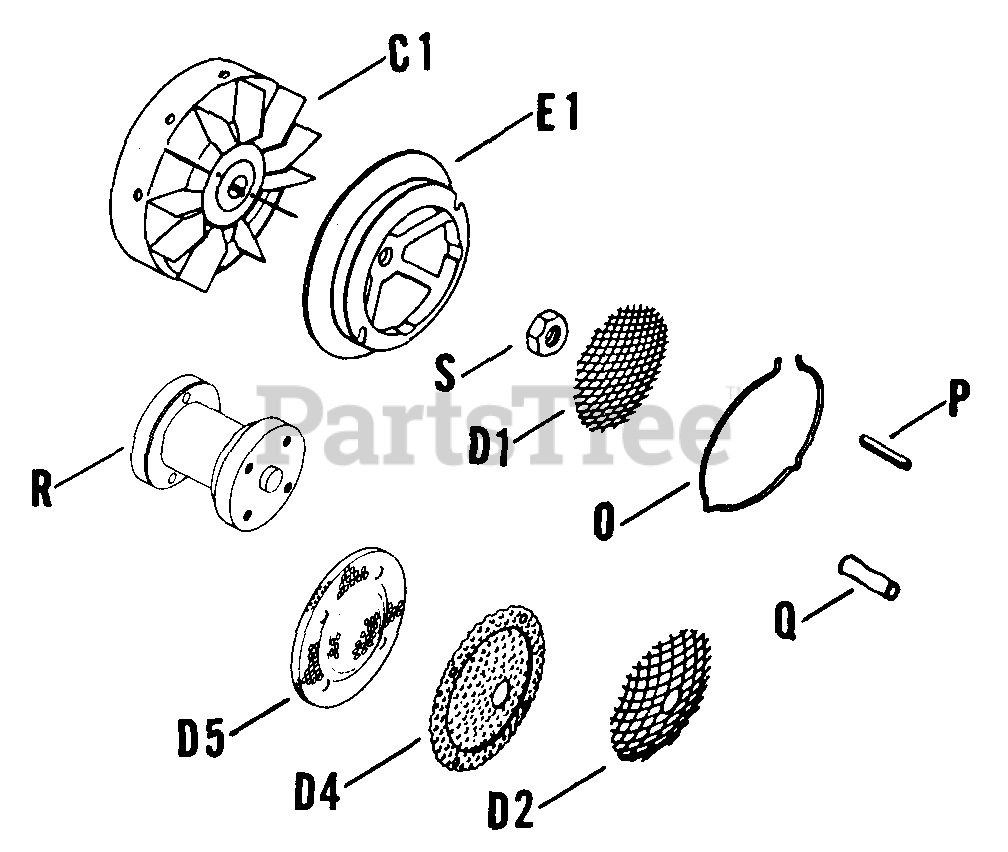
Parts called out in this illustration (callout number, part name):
C1	FLYWHEEL - DISCONTINUED
D1	SCREEN, GRASS
E1	PULLEY - USE 41 093 02
O	RETAINER
P	KEY - (#DSC)
S	NUT - USE X-119-14
